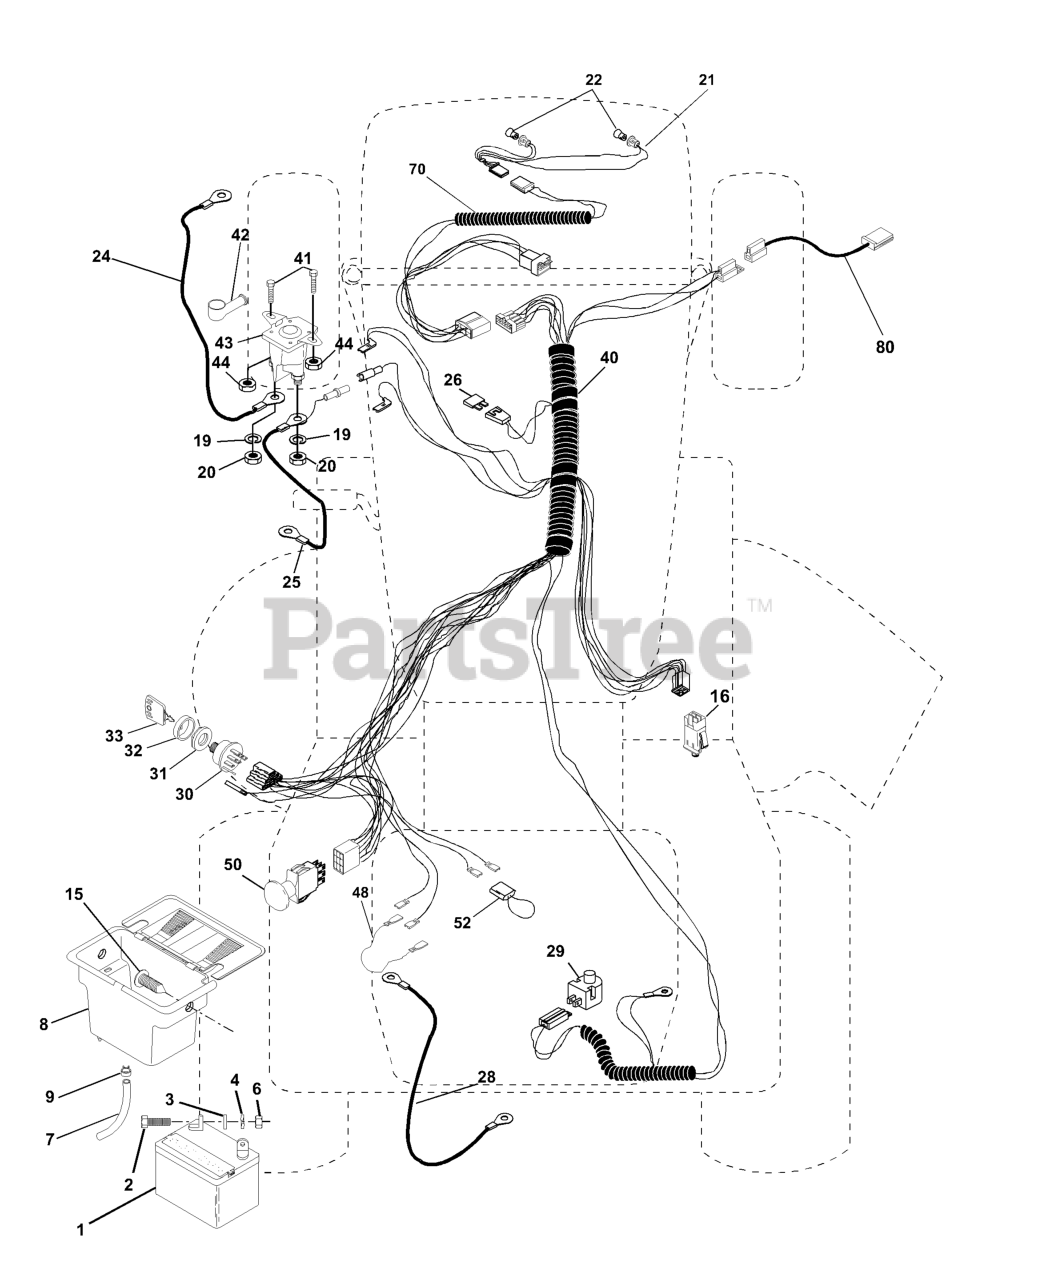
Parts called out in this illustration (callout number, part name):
1	BATTERY
2	BOLT.HEX.1/4.X.3/4.DICHROMATE
3	WASHER
4	LOCKWASHER
6	NUT
7	TUBE BATTERY DRAIN
8	BATTERY CASE
9	HOSE CLAMP T
15	FASTERER SNAP-IN
16	SWITCH INTERLOCK
19	LOCKWASHER
20	NUT
21	HARNESS LIGHT SOCKET
24	BATTERY CABLE GT
25	CABLE BATTERY
28	CABLE T
29	RP.SWITCH.PLUNGER.NC.GRAY
30	SWITCH.IGNITION.4.POSITION
31	NUT IGNITION
32	COVER SWITCH KEY
33	KEY.MOLDED.GENERIC
40	HARNESS IGN ELEC P/L
41	BOLT
42	TERMINAL COVER
43	SOLINOID
44	Nut Keps Hex 1/4-20 Unc
48	ADAPTER.AMMETER
50	SWITCH-PTO
52	WIRE PROTECTION LOOP
70	HARNESS ENG KOHLER
80	HARNESS, CLUTCH
